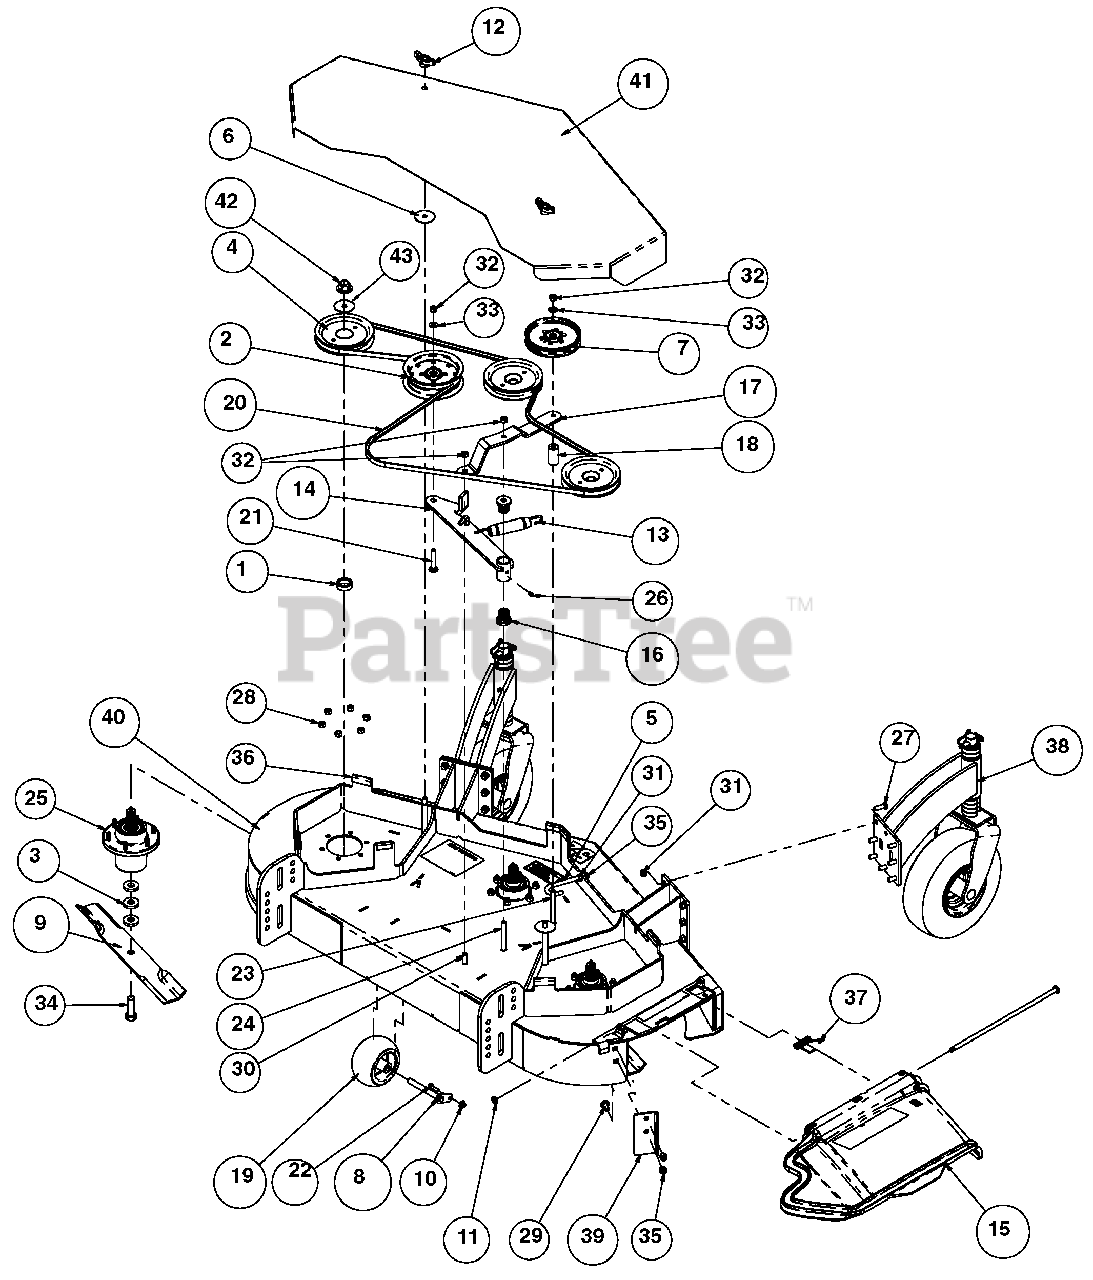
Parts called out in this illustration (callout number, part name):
1	Spacer, 1.500 x 1.000 x .510 Y
2	Pulley, Flat 5.0 x .38 W/Bearing
3	Washer, Blade
4	Pulley, Spline Spindle LSE
5	J-Bolt, 3/8-16 x 4.00 Y
6	Washer, .402 x 2.00 x .055 Fend Y
7	Pulley, FLAT 5.00 x .375 W/Bearing
8	Pivot, Retainer Weld
9	Blade, 18"
10	Nut-1/4" Flange Prevailing Tor
11	Retainer
12	Knob, Locking
13	Spring, Tension
14	Arm, Idler
15	Chute Discharge Assist
16	Bearing, FLG M10 x M25 x M27 Fluted
17	Strap, Idler Pulley
18	Spacer
19	Wheel, Gage
20	BELT, HB 109.3 EL AMD
21	Bolt, 3/8-16 x 2.25 CRG 5 Y
22	Bolt, 1/4-20 x 1.00 SQU SN Y
23	Bolt, 3/8 x 4 Short Neck Round Head
24	Bolt, 3/8-16 x 3.50 CRG 5 Y
25	Assembly, Spindle Housing
26	Fitting, 1/4-28 Straight Grease Zerk
27	Bolt, 3/8-16 x 1.00 Hex 5 Y
28	Nut, 3/8-16 STD Hex GR5 Y
29	Bolt, 3/8-16 x 1.00 CRG 5 SN Y
30	Bolt, 3/8-16 x 1.25 CRG 5 Y
31	Locknut, 3/8-16 Whiz Y
32	Locknut, 3/8-16 Crown Y
33	Washer, .406 x .813 x x .065 Flat Y
34	Bolt, 5/8-11 x 2.00 Hex 8 Y
35	Locknut, 3/8-16 Nyloc Y
36	Trim 1/4
37	Spring, Discharge Chute
38	Assembly, Wheel & Strut (see page 26 for parts)
39	Plate, Extender 48" Hydro
40	Weldment, 52 Gravely Deck w/Decals
41	Weldment, 52 Gravely Deck Shield w/Decal
42	Locknut, 3/4-16 Crown
43	Washer, .75 x 1.312 x .120
